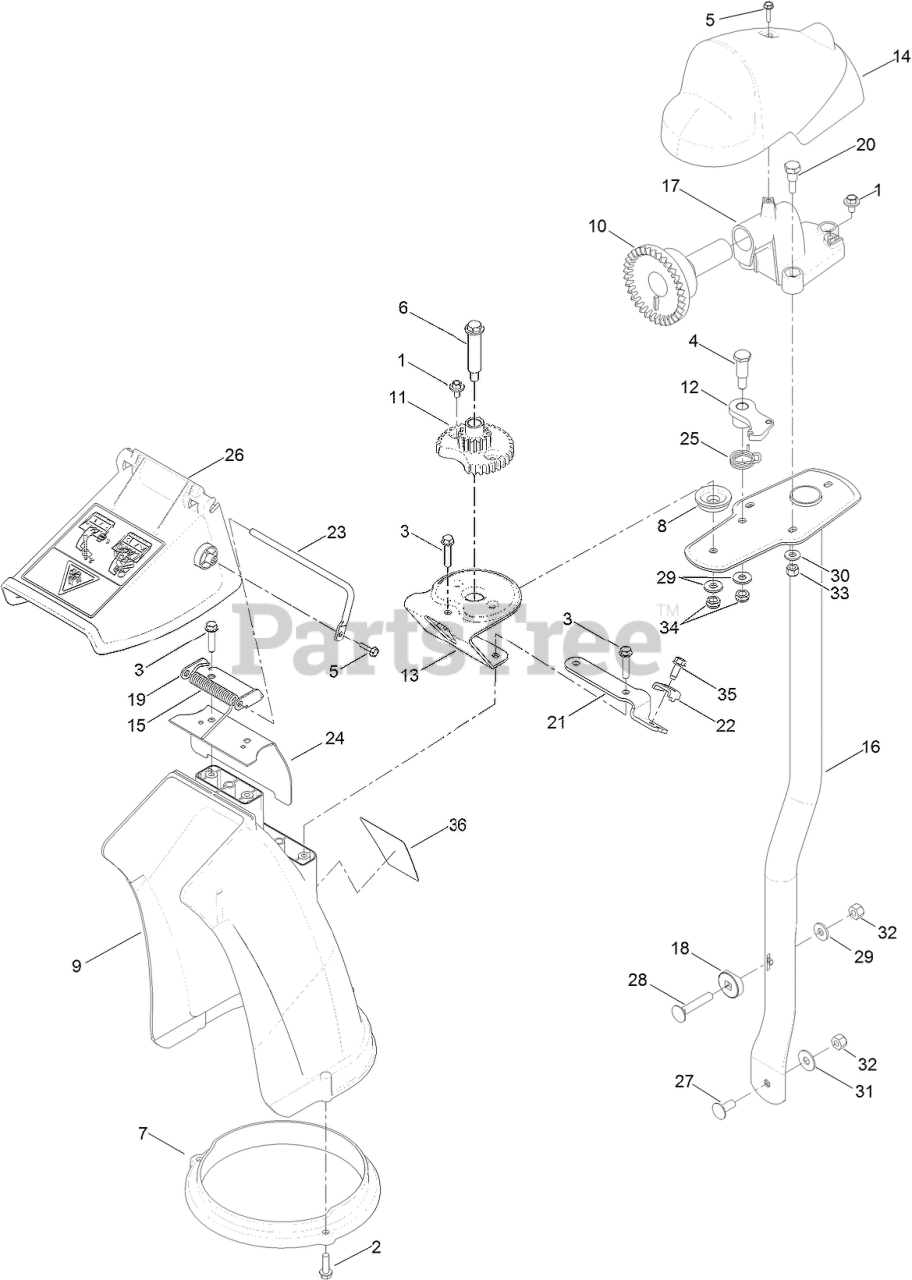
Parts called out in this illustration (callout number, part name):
1	SCREW AND WASHER ASM
2	SCREW-HWH
3	SCREW-PLASTITE
4	SCREW-SHOULDER
5	SCREW-HWH
6	BOLT-SHOULDER
7	RING-CHUTE
8	SPACER-CHUTE
9	CHUTE-DISCHARGE
10	GEAR-FACE
11	GEAR-CHUTE
12	LATCH-CHUTE
13	BRACKET-SUPPORT, CHUTE
14	COVER-GEAR, CHUTE
15	SPRING-TORSION
16	TUBE-SUPPORT
17	MOUNT-GEAR, FACE
18	WASHER-CURVED
19	BRACKET-DEFLECTOR
20	SCREW-SHOULDER
21	BRACKET-CABLE, CLAMP
22	CLAMP-CABLE
23	ROD-DEFLECTOR
24	SEAL-CHUTE
25	SPRING-TORSION
26	DEFLECTOR-CHUTE, CE
27	SCREW-CARR
28	SCREW-CARR
29	WASHER-FLAT
30	WASHER-FLAT
31	WASHER-BELLEVILLE
32	NUT-LOCK, NI
33	NUT-LOCK, NI
34	NUT-LOCK, NI
35	SCREW-HWH
36	DECAL-GUARANTEE
